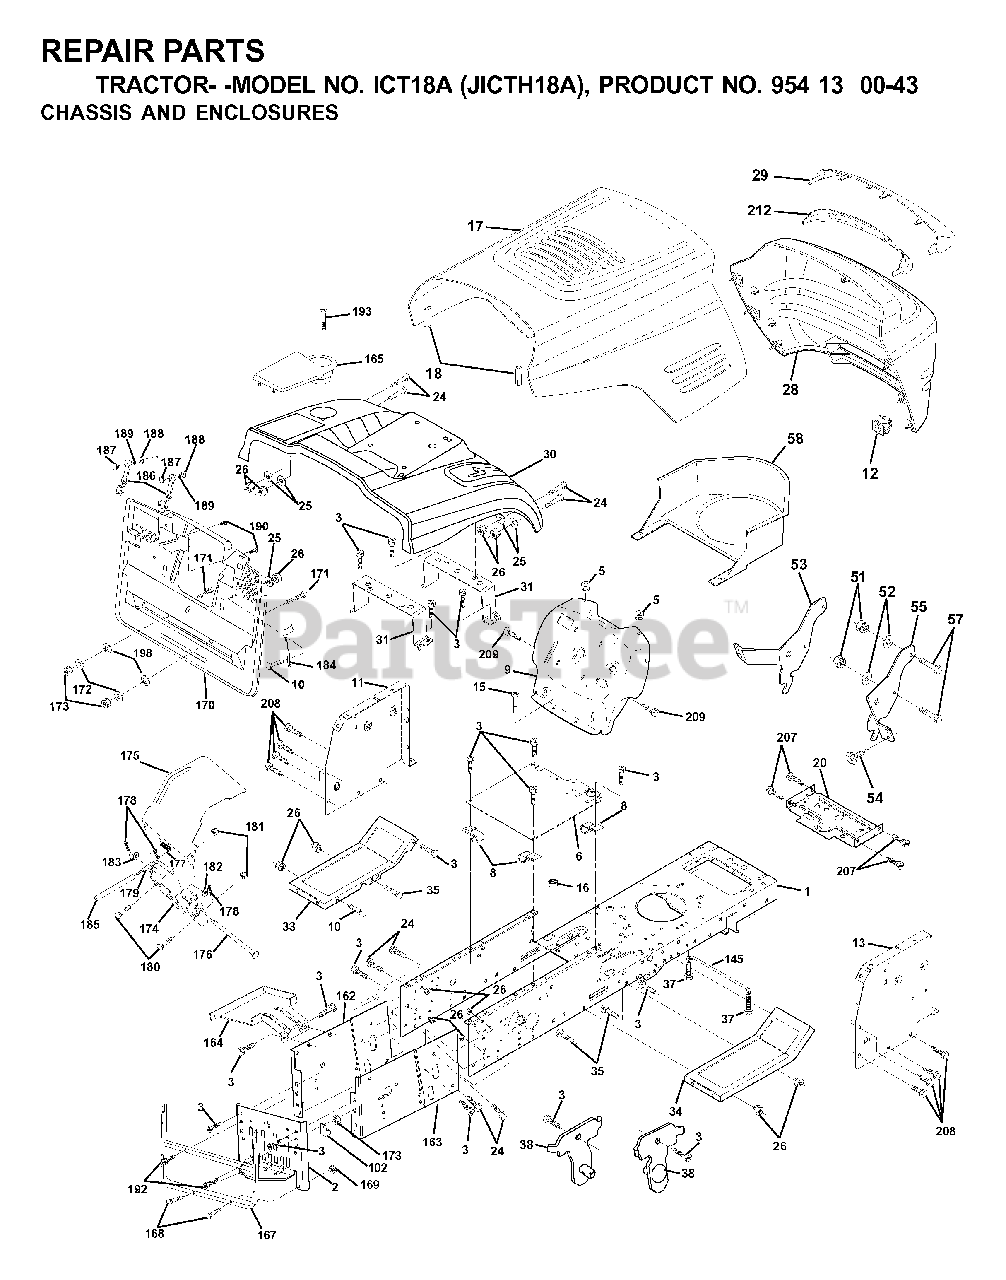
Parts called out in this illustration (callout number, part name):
1	CHASSIS STAMPING
3	SCREW 3/8-16X3/4
5	BUMPER.RUBBER.HOOD
6	SADDLE FLAT
8	CLIP,INSULATOR
10	BOLT D
11	PANEL DASH LH
13	DASH PANEL RH
16	NUT
18	BUMPER HOOD T
20	PLATE MTG
25	WASHER
26	NUT
31	BRACKET SUPPORT FENDER
38	BRACKET
51	LOCKNUT
57	BOLT
58	AIR CONDUCTOR
102	CLIP T
145	ROD PIVOT CHASSIS/HOOD
164	SUPPORT
168	BOLT.ROUND.HEAD.SQUARE.NECK
169	NUT T
170	COVER BACKPLATE
172	WASHER
176	HINGE PIN
177	SPRING COVER LH
178	COTTER PIN
179	ROD PIVOT
180	BOLT RB
181	LOCKNUT
184	BRACKET
185	TUBE LEVER
186	LATCH ASSY
187	WELDNUT
189	LOCKWASHER
190	SCREW
192	SCREW LT
193	SCREW, TRUSS 1/4-20 X 3/4"
207	SCREW, 5/16-18 X 1/2
208	SCREW 3/8-16X1/2
209	SCREW, 3/8-16X3/4
